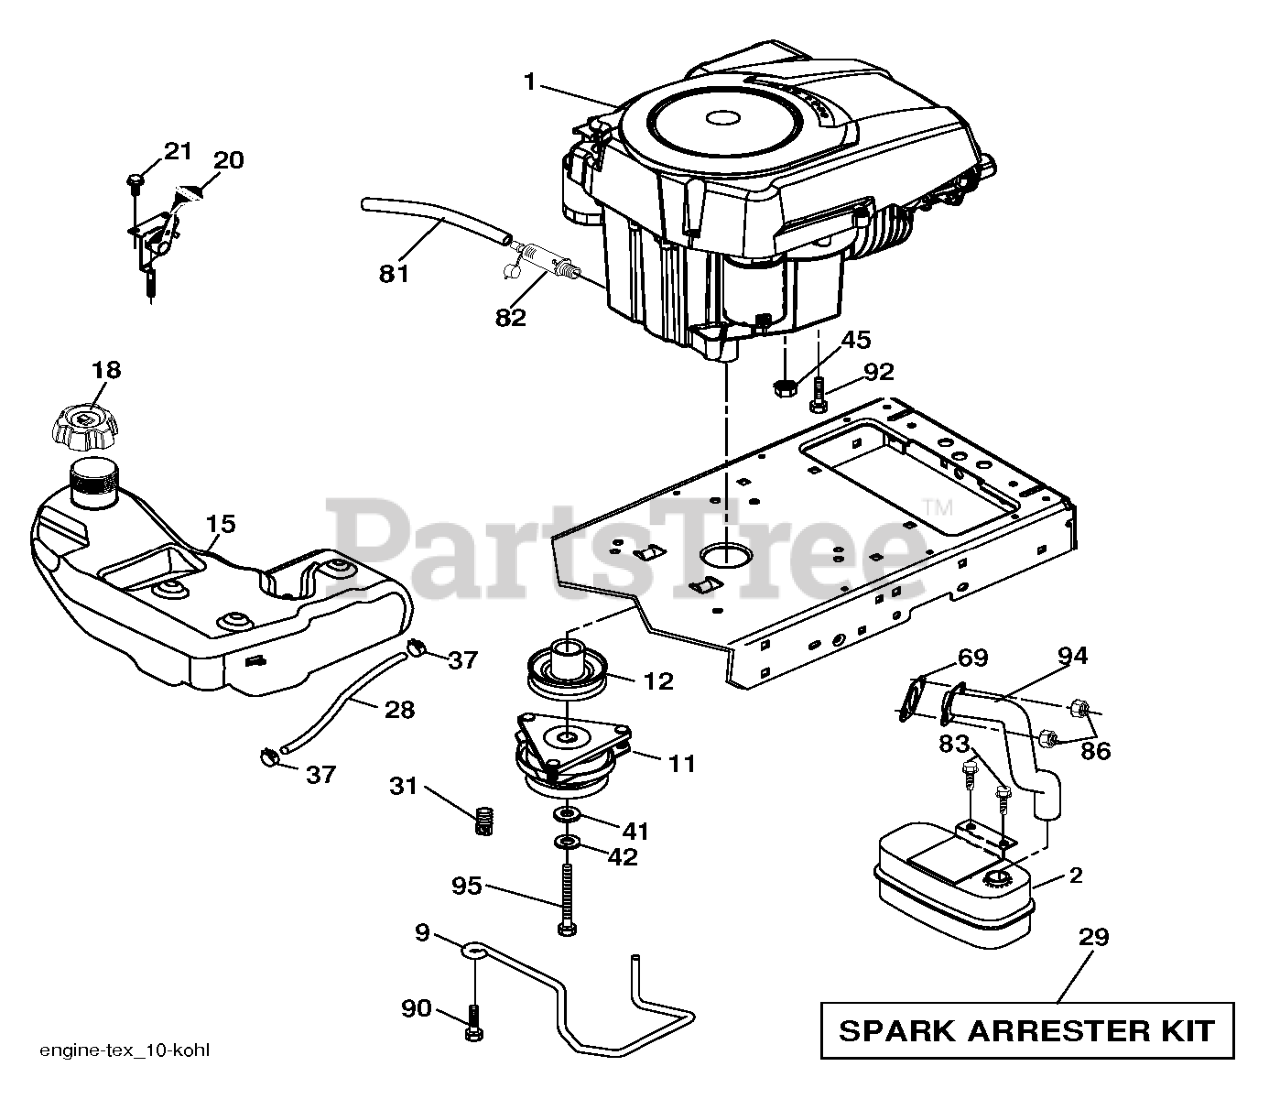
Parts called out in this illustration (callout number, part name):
2	MUFFLER.SINGLE.CYL.KOHL/B&S
9	KEEPER.BELT.ENGINE.3.25 (3 2)
11	RB.CLUTCH.OGURA.4.4.PD
12	PULLEY.ASM.ENG.OGURA.3
15	TANK.FUEL.SIDE-FILL.3.NON-EPA
18	CAP.FUEL.TANK.3"GREY
20	CONTROL.TH/CK.C.
21	SCREW
28	REPL BY 532 00 85-43
29	KIT.SPARK ARRESTOR 794945 B&S
37	HOSE CLAMP
42	LOCKWASHER
45	NUT
69	GASKET.EXHAUST.KOHLER
81	TUBE, DRAIN OIL ASM.
82	PLUG DRAIN OIL EASY
83	BOLT.5/16-18UNCX3/4 W/SEMS.BLK
86	NUT.HEX.FLANGE.TOPLOCK
90	SCREW 3/8-16X1
92	SCREW 3/8-16X1
94	RP.TUBE.EXHAUST.KOHL.COURAGE
95	BOLT HEX 7/16-20X4-1/4"
